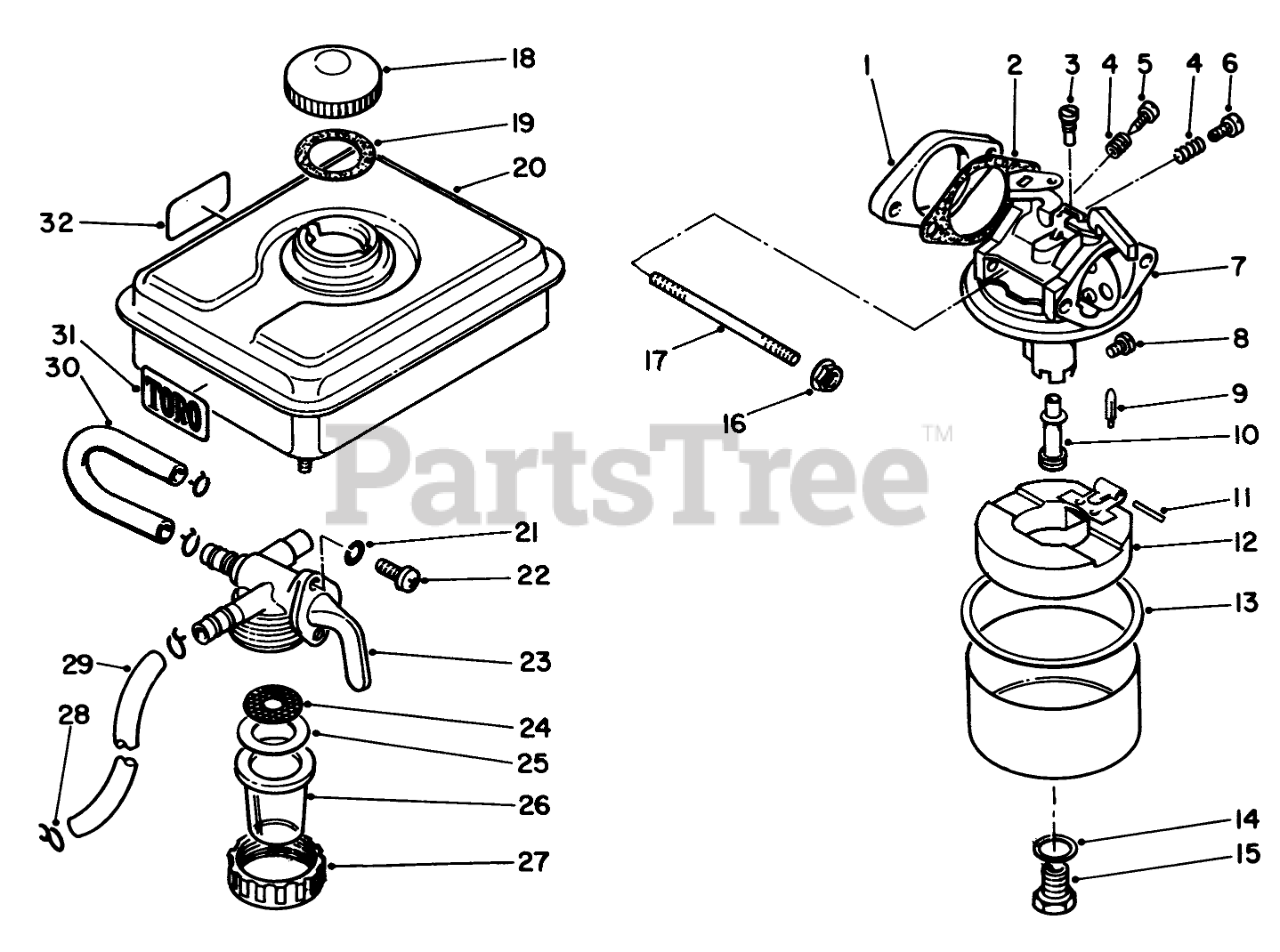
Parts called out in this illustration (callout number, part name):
1	INSULATOR
2	GASKET
3	PILOT JET
4	SPRING
5	ADJUSTER
6	SCREW
7	Carburetor Assembly (Incl. Ref. #8-15)
8	MAIN JET
9	NEEDLE VALVE
10	NOZZLE
11	Pin
12	Float
13	GASKET
14	GASKET
15	Bolt
17	Stud Bolt
19	GASKET
20	Tank-Fuel
21	Lockwasher
22	Screw
23	Petcock Assembly (Incl. Ref. #24-27)
24	FILTER
25	GASKET
31	Decal-Toro Logo
32	Decal-Instruction
